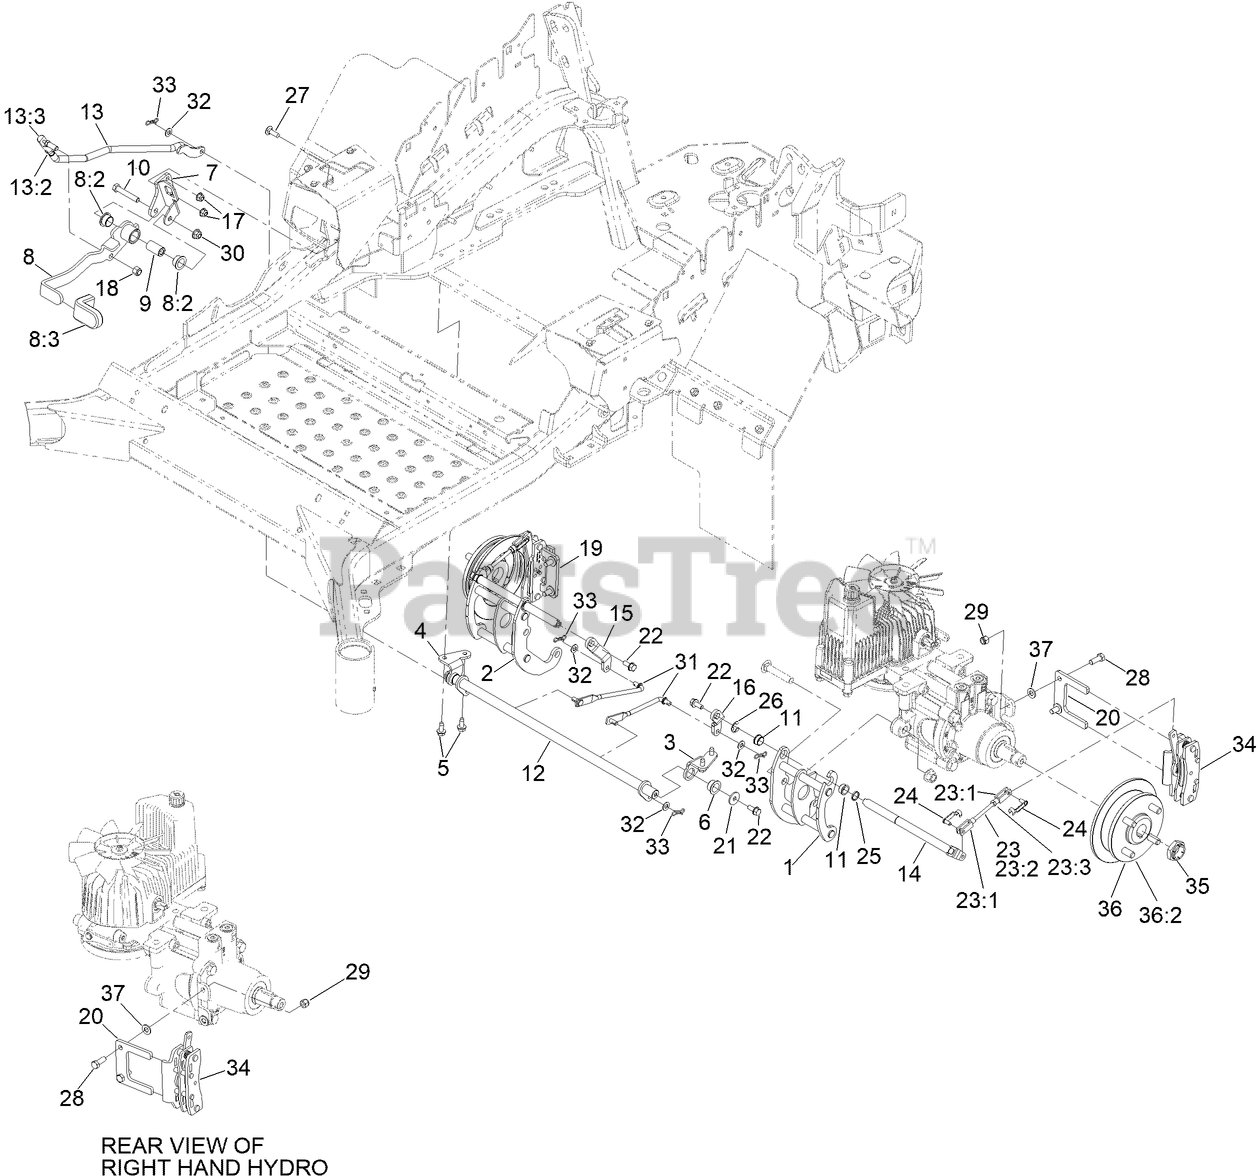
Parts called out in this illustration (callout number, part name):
1	MOUNT-BELLCRANK, LH
2	MOUNT-BELLCRANK, RH
3	MOUNT-PIVOT, LH
4	MOUNT-PIVOT, RH
5	SCREW-HWHTF
6	BUSHING-FLANGE
7	BRACKET-MOUNT
8	BRAKE LEVER ASM
8:2	BUSHING-FLANGE
8:3	GRIP-LEVER
9	HANDLE-PIVOT, BRAKE
10	SCREW-HH
11	BUSHING
12	SHAFT-CROSS
13	FRONT LINKAGE ASM
13:2	END-TIE ROD, RH
13:3	NUT-HJ
14	BELLCRANK,
15	ARM-INNER, RH
16	ARM-INNER, LH
17	NUT-HF, NI
18	NUT-LOCK
19	CALIPER-BRAKE, RH
20	PLATE-MOUNT, BRAKE
21	WASHER-FLAT
22	SCREW-HHF
23	REAR LINKAGE ASM
23:2	LINKAGE, REAR
23:3	NUT-JAM
24	PIN-CLEVIS, SPRING
25	SPACER
26	E-RING
27	BOLT-CARR
28	SCREW-HH,
29	NUT-LOCK
30	NUT-HF, NI
31	MID-LINK, SHORT
32	WASHER-PLAIN
33	PIN-COTTER, LOCKING
34	CALIPER-BRAKE, LH
35	LOCKNUT
36	WHEEL HUB ASM
36:2	STUD-WHEEL
37	WASHER-FLAT
